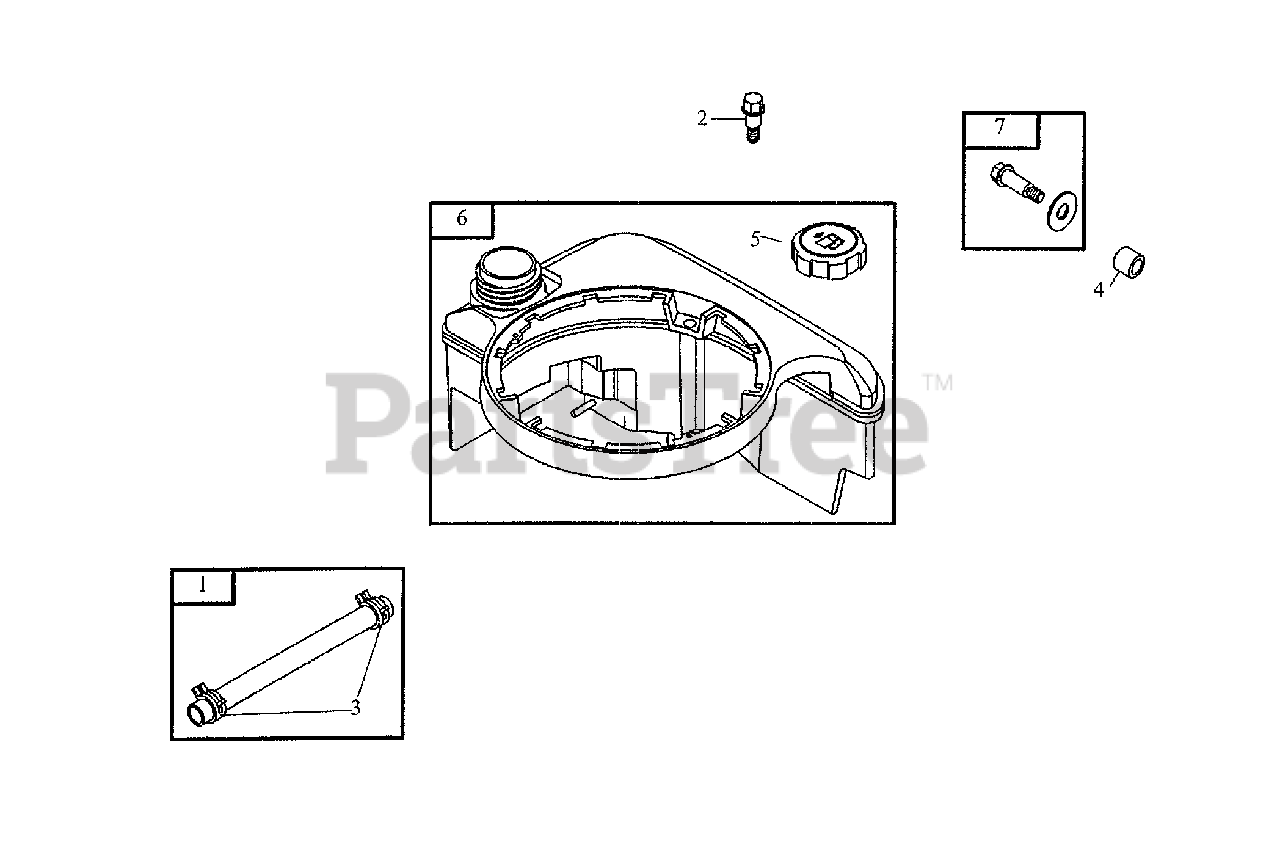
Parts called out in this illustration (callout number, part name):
1	Fuel Line
2	Screw
3	Clamp, Hose
4	Spacer, Fuel Tank
5	Cap, Fuel Tank
6	Tank, Fuel
7	Kit, Screw
